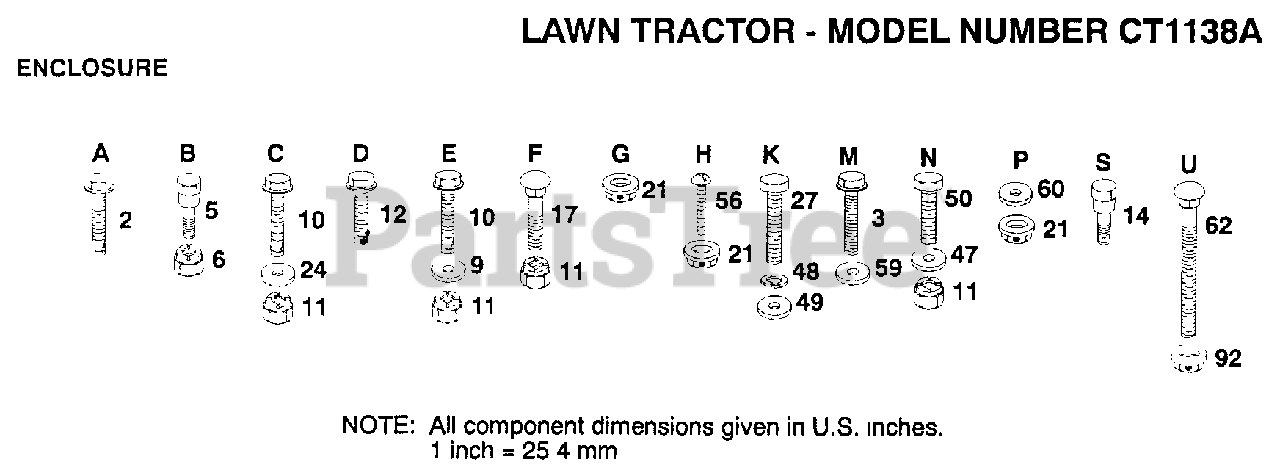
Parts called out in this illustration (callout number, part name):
2	SCREW
3	SCREW GTV
9	WASHER
12	SCREW LT
14	"BOLT,SHOULDER"
17	BOLT
21	PAL NUT LT
24	WASHER
27	BOLT
47	WASHER
48	LOCKWASHER
49	WASHER
50	BOLT
56	SCREW SPECIAL
59	WASHER
60	WASHER PM
62	BOLT
